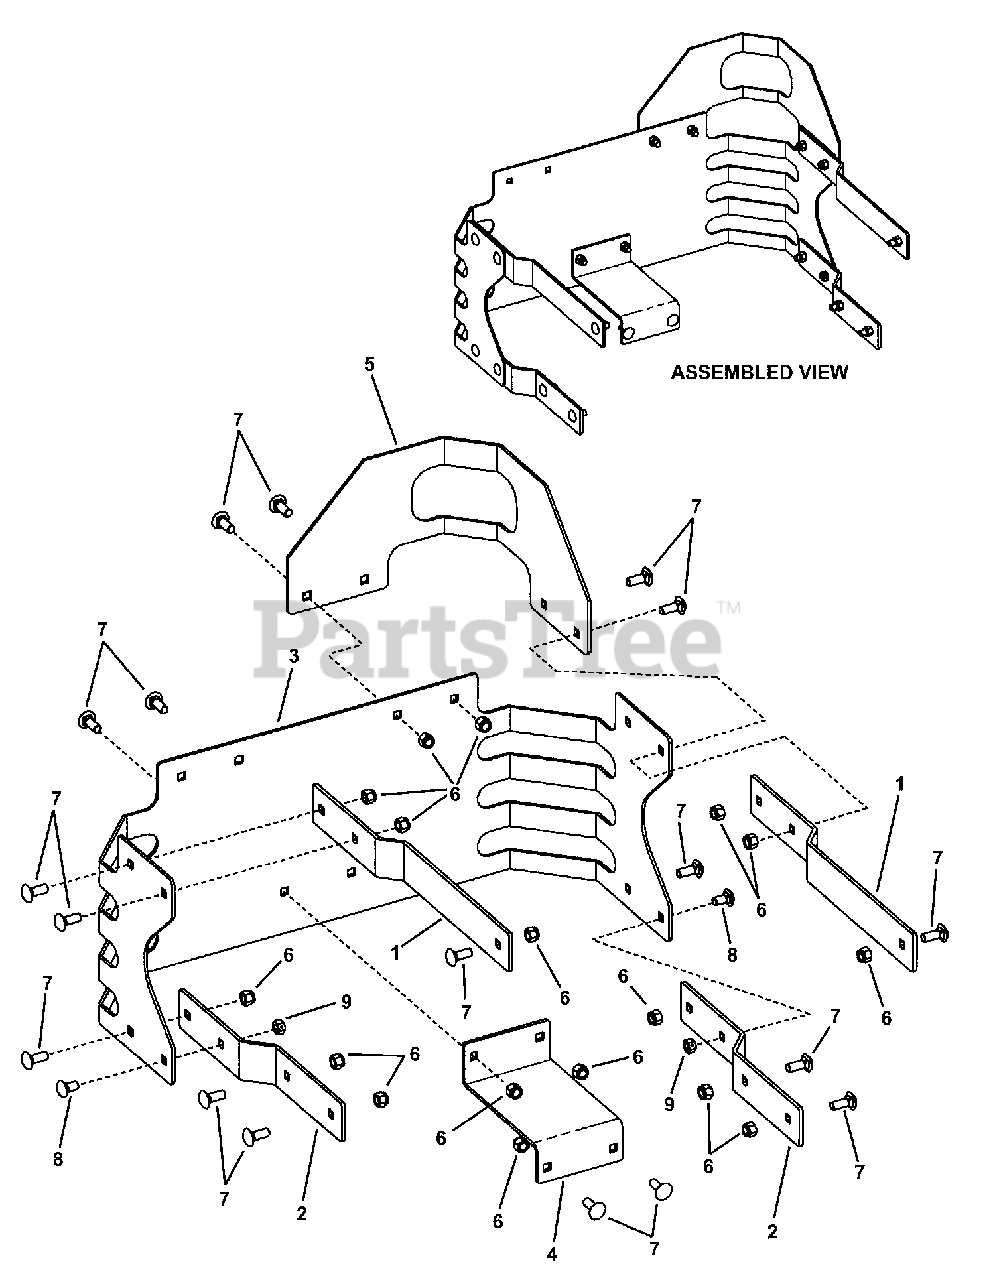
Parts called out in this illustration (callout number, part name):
1	UPPER BRACKET, Muffler Guard
2	MOUNT, Lower Muffler Guard
3	GUARD, Muffler (Back Plate)
4	REAR BRACE, Muffler Guard
5	GUARD, Muffler
6	NUT, 3/8-16 HEX NYLON LOCK
7	BOLT, 3/8-16 x 1" Square Neck Carriage GR 5
8	BOLT, 3/8-16 x 3/4" Square Neck Carriage
9	NUT, 3/8-16 Hex Center Lock
